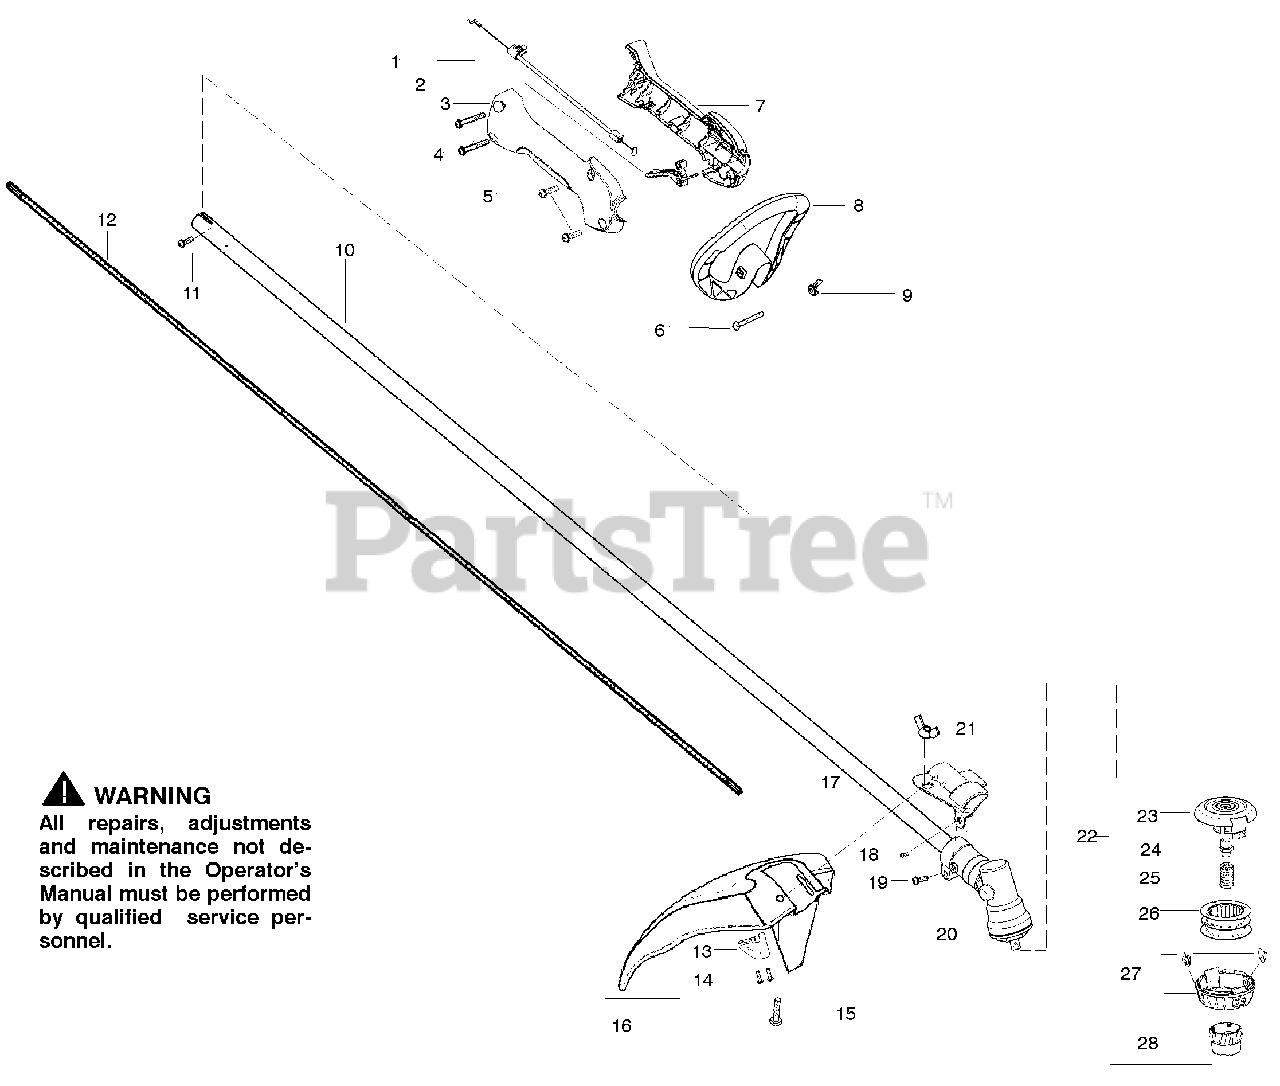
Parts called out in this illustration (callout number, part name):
1	Assy-Throttle Cable
3	Throttle Hsg. (Right)
7	Throttle Hsg. (Left)
8	Assy-Handle
9	Wingnut-Handle
10	Assy-Drive Shaft Hsg.
11	Screw
16	Kit-Shield Assy
17	Bracket-Shield
21	Wingnut
22	Assy - TNG7 Head
24	Adapter
25	Spring
26	Accy-Wound Spool
27	Kit-Cover and Eyelet
28	Knob
